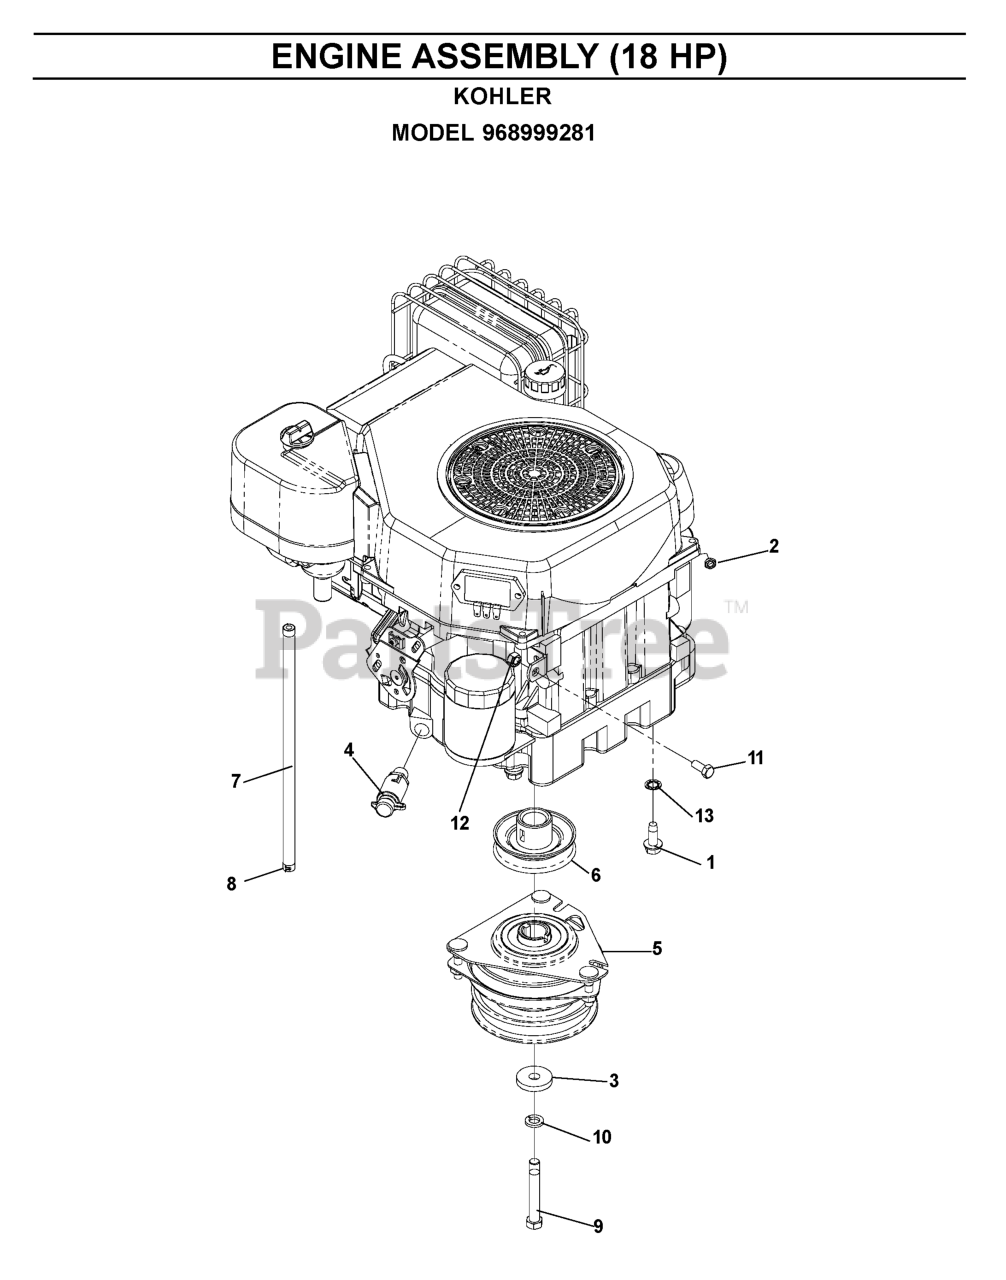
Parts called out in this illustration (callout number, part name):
1	BOLT 3/8-16 X 1.0
2	JAM NUT 1/4C (2 2 PW01)
3	CLUTCH, WASHER
4	OIL DRAIN FITTING
5	CLUTCH 90 FT/LB OGURA
7	FUEL LINE 5"
8	HOSE CLAMP
9	HEX SCREW 7/16-20 X 3
10	WASHER 7/16 LOCK
12	NUT 3/8C CENTERBLOCK
13	WASHER, 3/8 ITLW ZN
